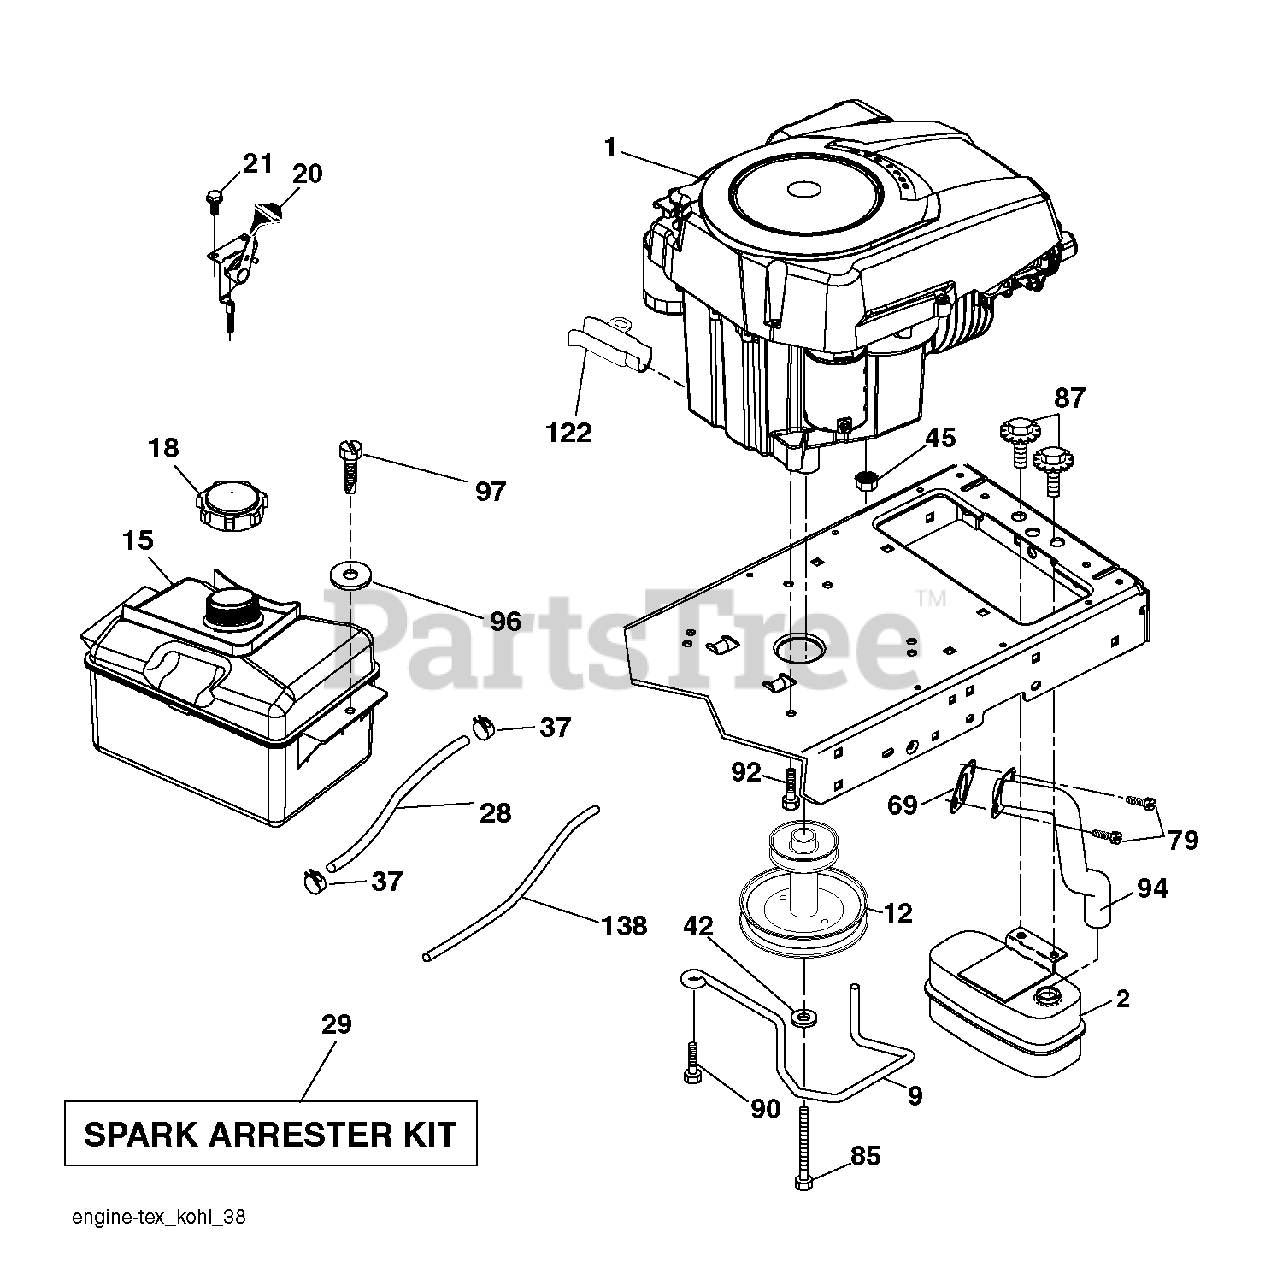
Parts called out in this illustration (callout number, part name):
2	MUFFLER.LT.BRIGGS.14HP.IC/OHV
9	KEEPER.BELT.ENGINE.3.25 (3 2)
12	PULLEY ENGINE
15	TANK.ASM.FRT.2.5 GAL.W/CAP.EPA
20	CONTROL.TH/CK.COBRA.KO
21	SCREW.#10 X 0.750.BOS
28	LINE.FUEL.20"FRONT.EMI
29	SPARK ARRESTOR KIT
37	HOSE CLAMP
42	LOCKWASHER
45	NUT
69	REPL BY 532 27 22-93
79	SCREW.SOCKET HD.5/16-1
85	BOLT HEX 7/16-20X4-1/4"
87	BOLT, 5/16-18 X 1 3/4
90	SCREW 3/8-16X1
92	SCREW 3/8-16X1
94	RP.TUBE.EXHAUST.KOHL.COURAGE
97	SCREW HEXWSHR 1/4-20X3/4
122	EXTENSION DRAIN OIL
138	RP PURGE LINE
